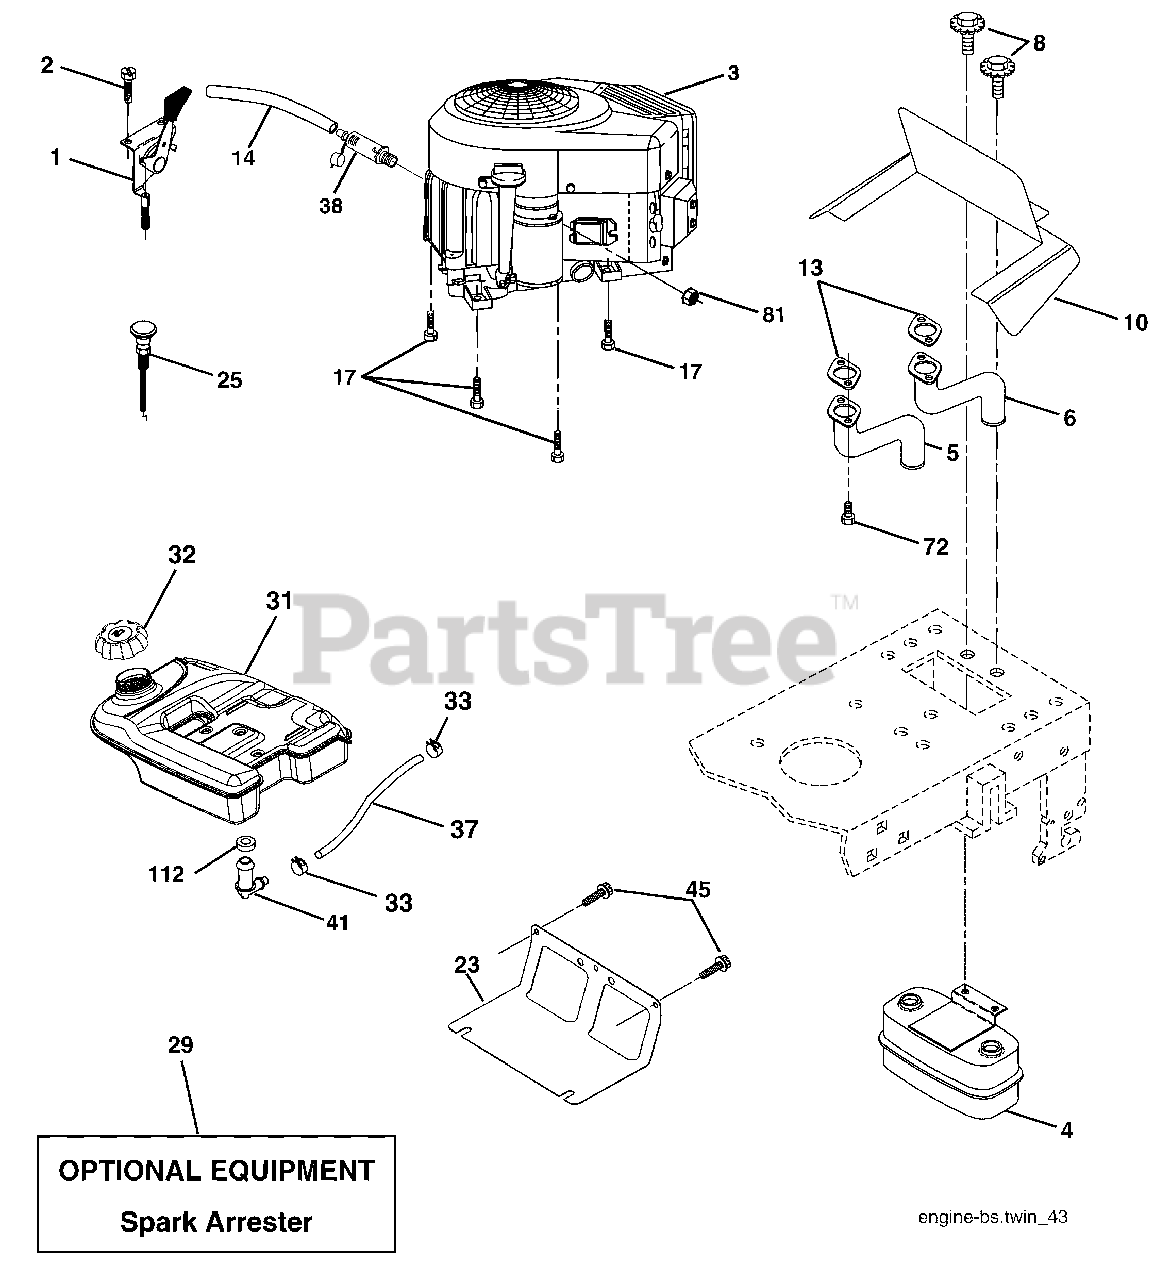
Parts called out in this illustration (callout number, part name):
1	Control Th/ch Flag
2	Screw Hex Thd Cut 1/4-20 x 1/2
5	Exhaust Tube LH
6	Exhaust Tube RH
8	Bolt 5/16-18 unc x 3/4
10	Shield Heat Muffler
14	Tube Drain Oil Easy
17	Screw 3/8-16 x 1-1/2
23	Shield Browning/Debris Guard
25	Control Choke
29	Kit Spark Arrestor
32	Cap Asm Fuel
33	Clamp Hose Black
37	Line Fuel
38	Plug Drain Oil Easy
41	Stem Tank Fuel
45	Screw Hex Wsh Thdr 3/8-16 x 3/4
72	Screw Socket Head 5/16-18 x 1
81	Nut Keps Hex 1/4-20 Starter Nut
112	Bushing
